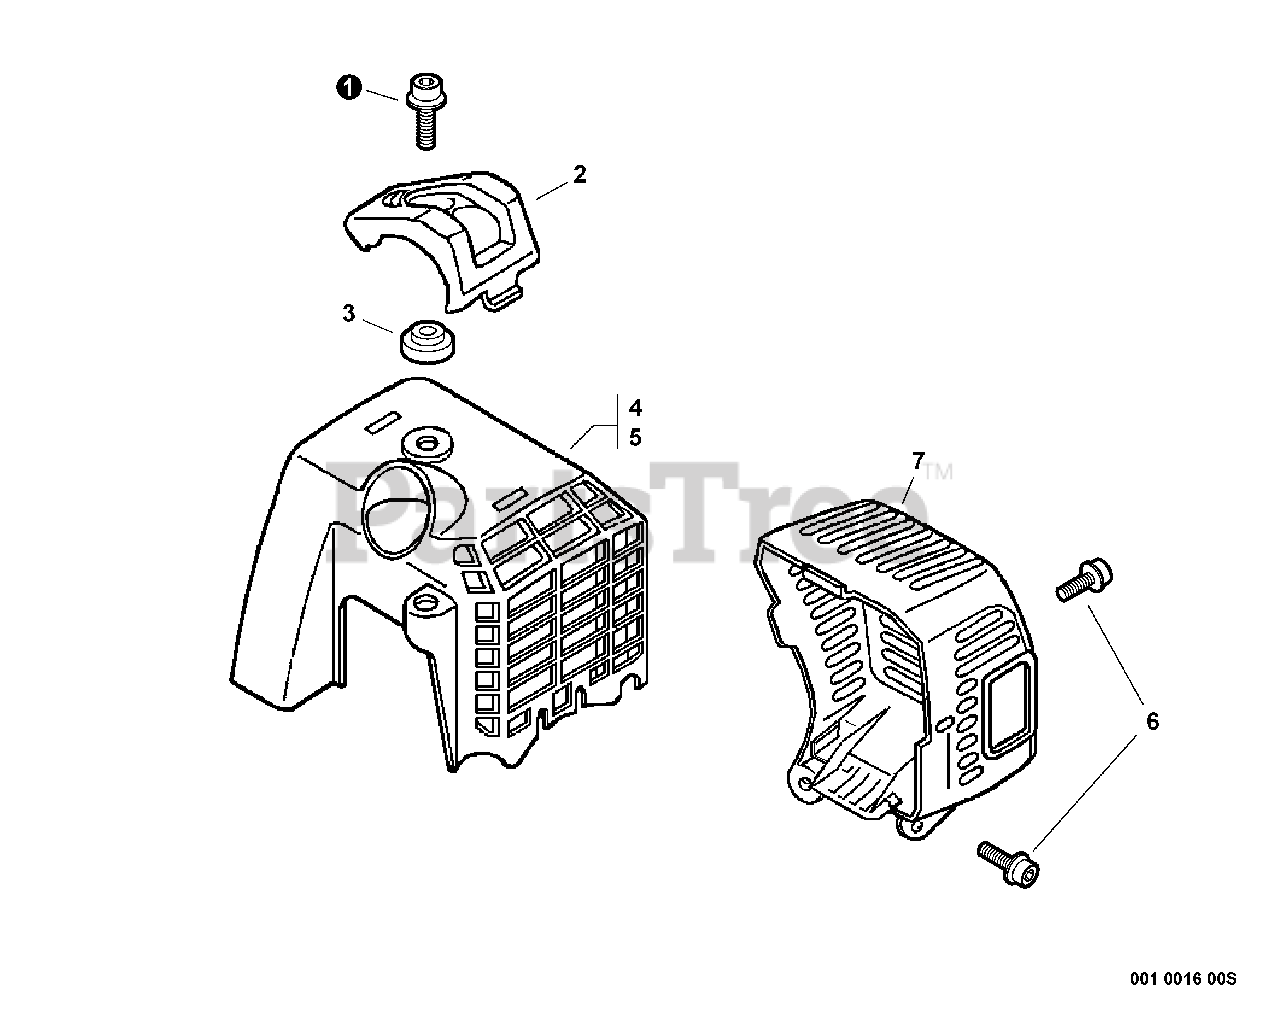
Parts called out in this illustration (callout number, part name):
1	SCREW - 5X16
2	GUARD - TOP
3	COLLAR - 5
4	COVER, ENGINE - BLACK
5	COVER, ENGINE - ORANGE
6	SCREW - 5X12
7	COVER, EXHAUST
